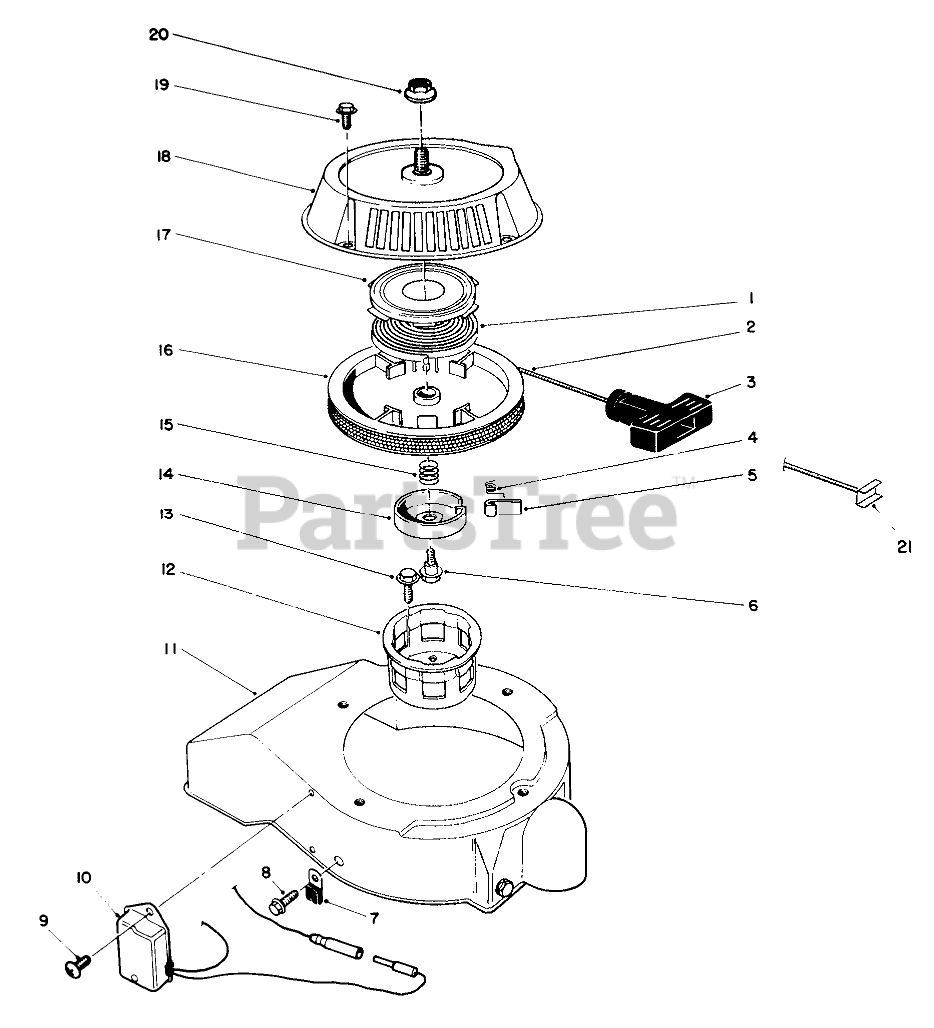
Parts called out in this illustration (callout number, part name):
1	Spring-Recoil (Incl. Ref. #17)
2	ROPE-STARTER
3	HANDLE-RECOIL
4	SPRING
7	CLAMP
9	SCREW
10	MODULE
11	SHROUD
12	CUP - STARTER
14	RETAINER
15	SPRING
17	Retainer-Recoil Spring
18	RECOIL CASE
19	MOUNTING SCREW
20	NUT (F/W & PPP)
21	Insert Handle
